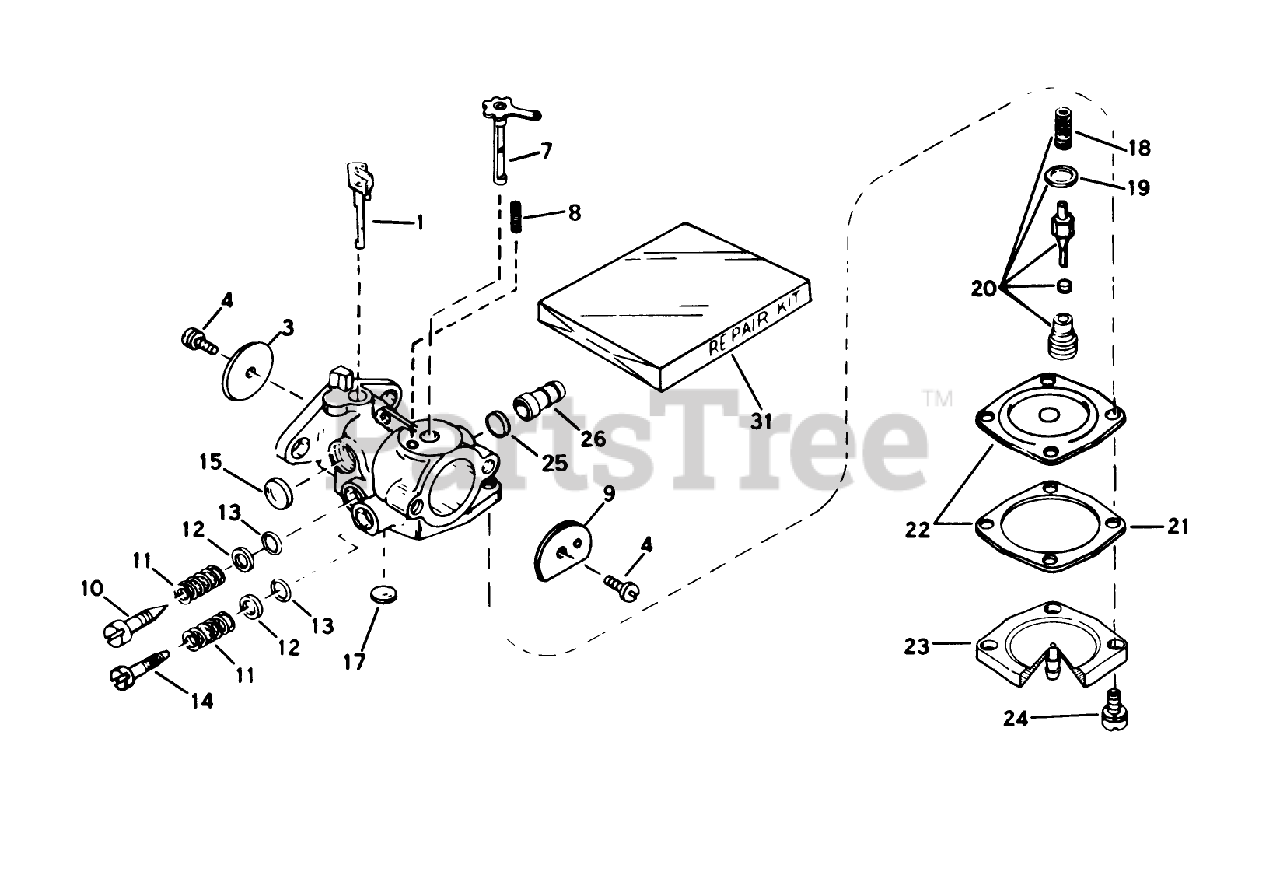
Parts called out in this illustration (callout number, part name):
1	Shaft/Lever-Throttle
3	Shutter-Throttle
4	Screw-Shutter
7	Shaft Lever Assembly
8	Spring-Positioning, Choke
10	Screw-Idle Adjustment
11	Spring
12	Washer
13	ORing
14	Screw Main Adjustment
15	Plug-Welch, Idle Mixture Well
17	Plug Welch
18	Spring-Valve
19	Gasket-Valve Seat
20	Inlet Needle, Seat, Spring Gasket Assy. (lncl. #1819)
21	Gasket-Diaphragm
22	Diaphragm Ass. (Incl. No. 21)
23	Cover-Diaphragm
24	Screw
26	Fitting-Fuel
31	Kit-Repair
